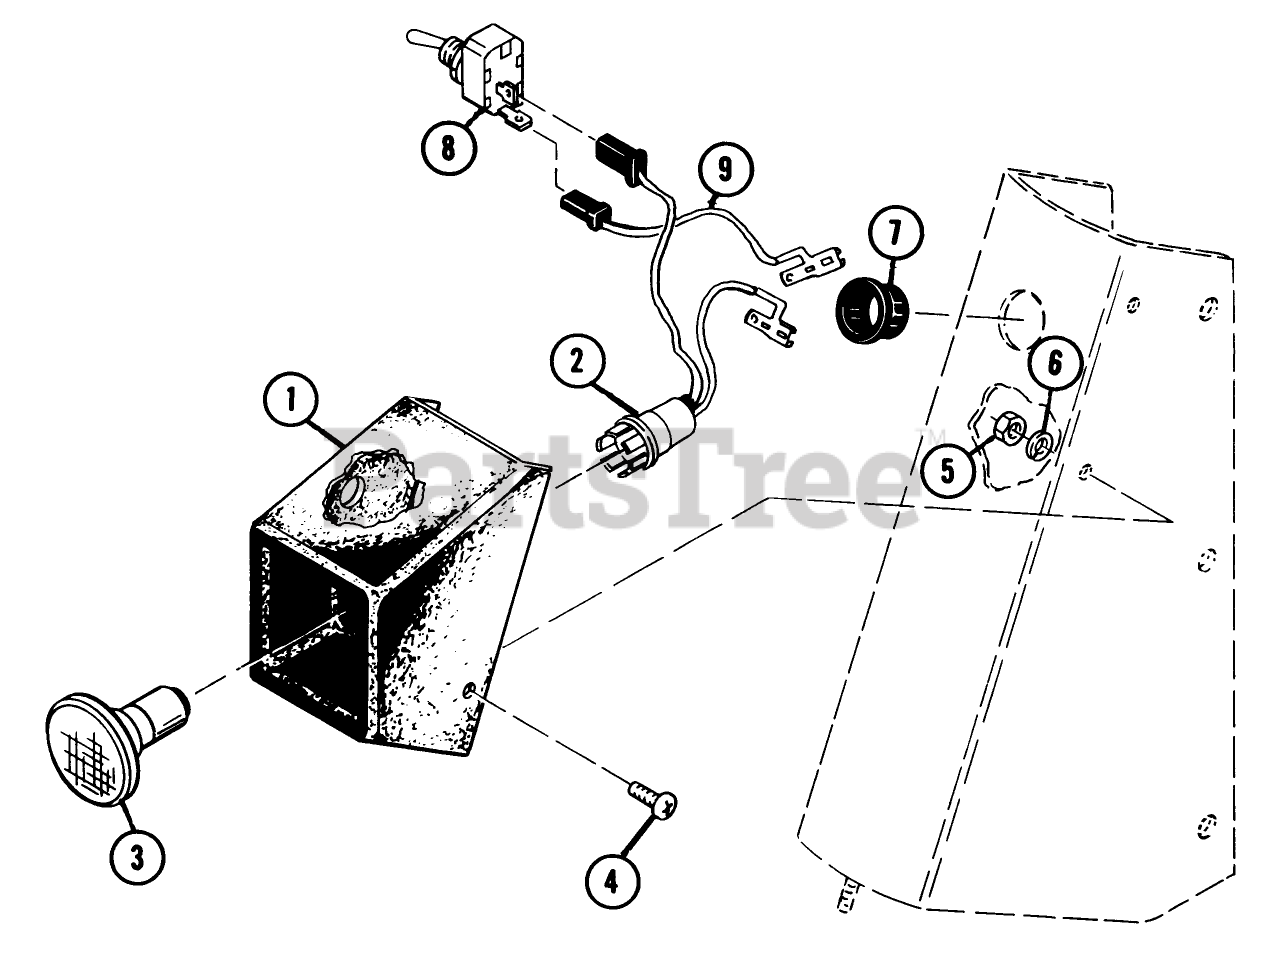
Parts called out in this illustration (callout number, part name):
1	Shroud, Plastic
2	Socket Assembly
3	Bult, 36 Volt Sealed Beam
4	MACH. SCREW
5	Nut
6	Washer
7	Bushing
8	SWITCH-LIGHTS
9	Wiring Assembly
